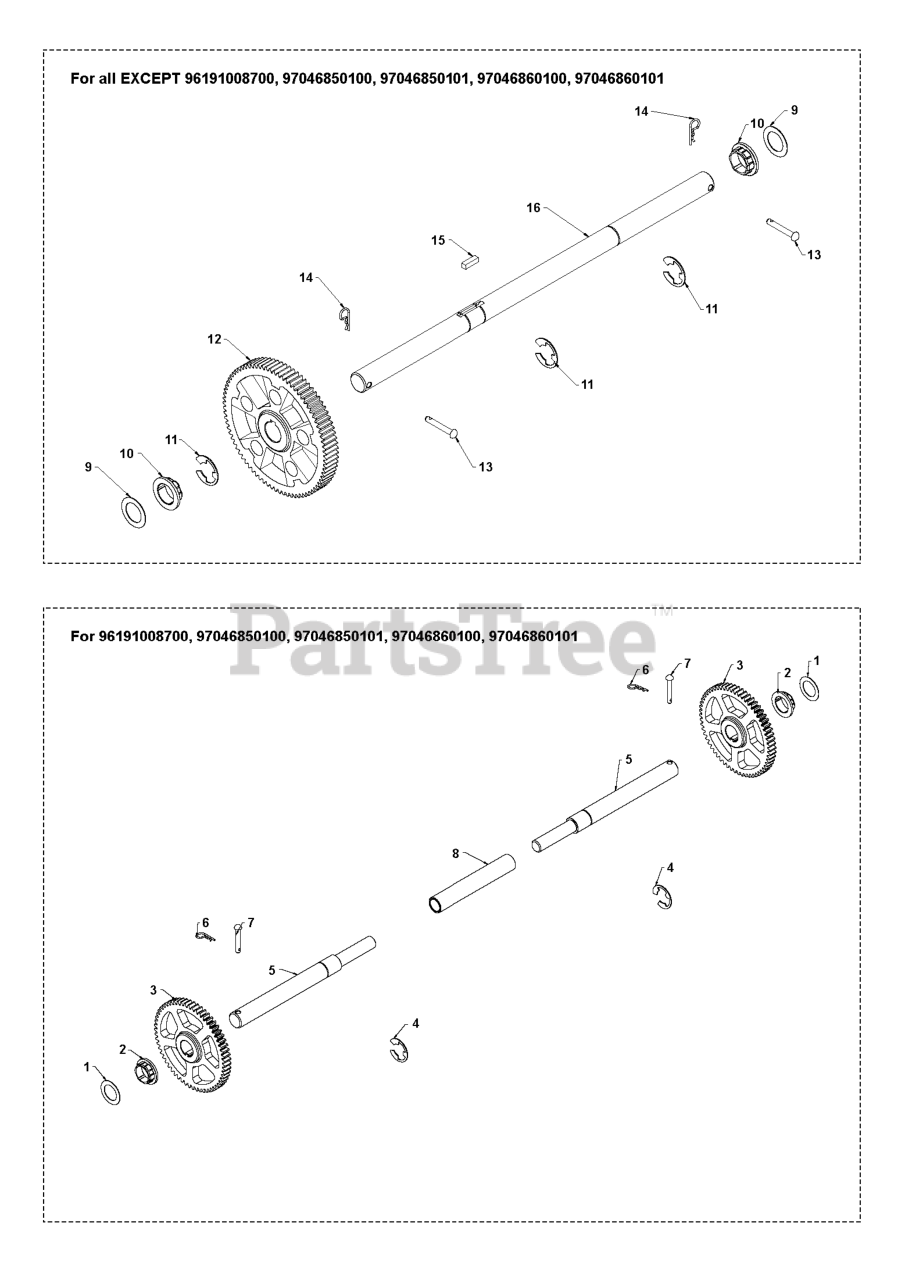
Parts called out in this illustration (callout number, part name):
1	WASHER 1.00
2	BUSHING,HEX BUSHING (1
2	BUSHING.HEX.1.SHAFT
3	GEAR.59T
3	GEAR 80T DRIVEN_2PC
4	E RING HYT
5	AXLE AXLE, SPLIT SHAFT
6	RETAINER M
7	RIVET,DRILLED
8	SLEEVE SLEEVE, AXLE SLEEVE
9	WASHER 1.00
10	BUSHING,HEX BUSHING (1
10	BUSHING.HEX.1.SHAFT
11	E RING HYT
12	GEAR.80T.DRIVEN.2PC
12	GEAR 80T DRIVEN_2PC
13	RIVET
14	RETAINER M
15	KEY, SQUARE 1/4 X .875
16	SHAFT SHAFT,AXLE,
